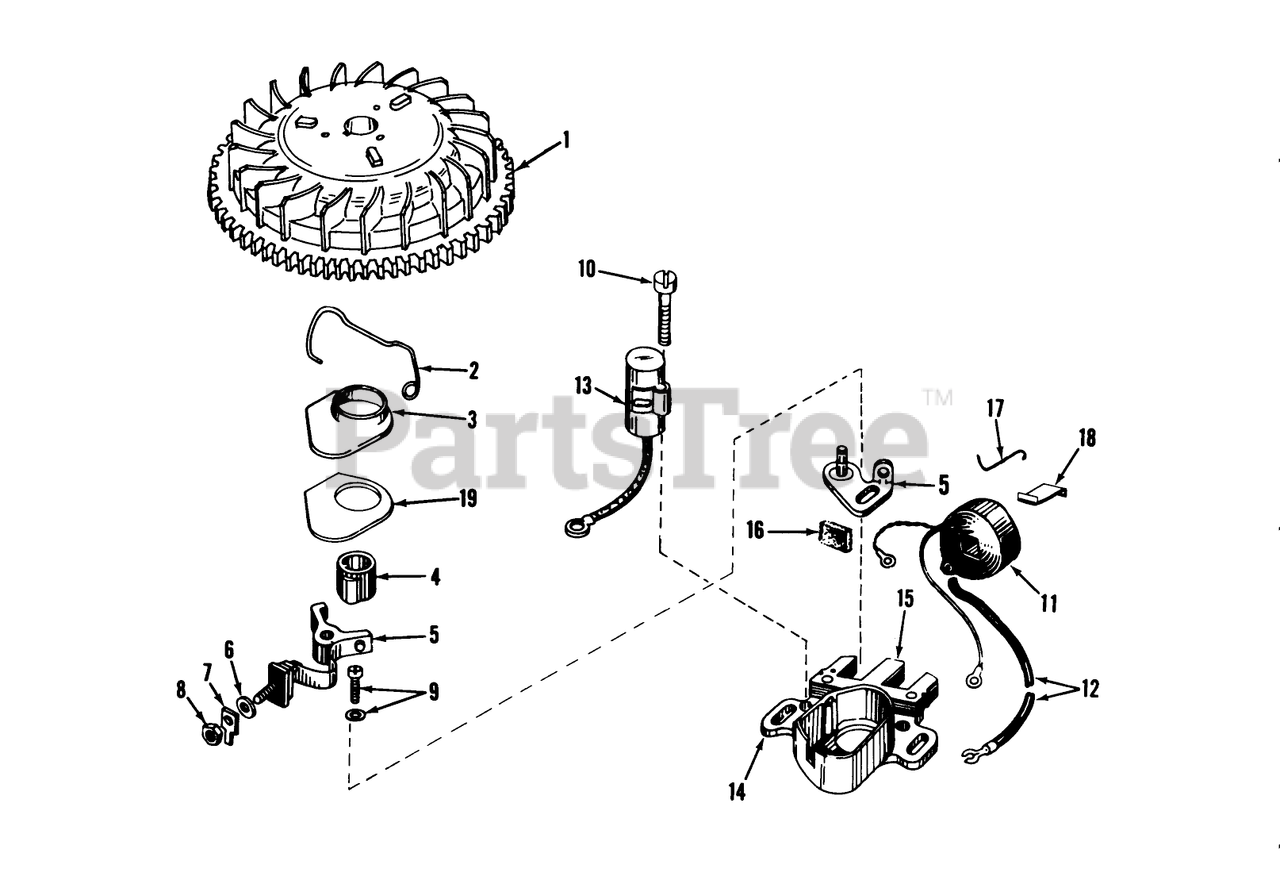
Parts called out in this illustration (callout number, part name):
1	FIywheel
2	Spring Breaker Box
3	Cover, Dust
4	Cam, Breaker
5	Breaker Assy.
6	Washer
7	Terminal
8	DECAL
9	Breaker Screw
10	Condenser Screw
11	Coil Assy. (Incl. No. 12)
12	Wire, Lead
13	Condenser
14	Core Plate
15	Stator Assy., (Incl. Nos. 2, 3, 5 thru 14 16 thru 19)
16	Felt,Cam Wiper
17	Clip, Coil
18	Spring Coil Wedge
19	Gasket Dust Cover
